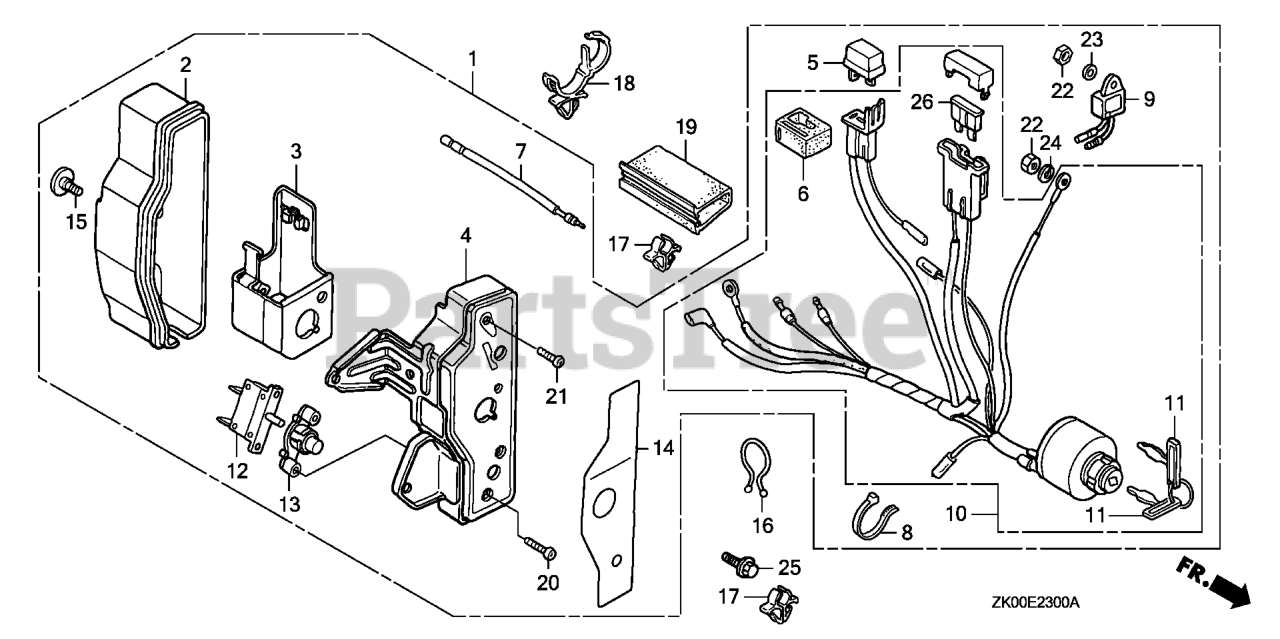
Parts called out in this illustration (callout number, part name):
1	BOX ASSY., CONTROL (EXP,10A) *R280* (POWER RED) (NOT AVAILABLE)
2	CASE, CONTROL
3	BRACKET, CASE MOUNTING
4	PANEL, CONTROL *R280* (POWER RED)
7	SUB-WIRE HARNESS
8	BAND
9	ALERT UNIT, OIL
10	SWITCH ASSY., COMBINATION (10A CHG/RCM)
11	KEY
14	MARK, CONTROL BOX (EXTERNAL-REGULATOR)
15	SCREW, SPECIAL (6X12)
16	CLIP, PURSE LOCK
17	CLIP, CORD
18	STRAP, WIRE HARNESS (25MM) (BLACK)
19	TUBE, FASTENER (30)
21	SCREW, PAN (4X12)
22	NUT, HEX. (4MM)
23	WASHER, PLAIN (4MM)
24	WASHER, SPRING (4MM)
25	BOLT, FLANGE (6X10)
26	FUSE, BLADE (15A)
